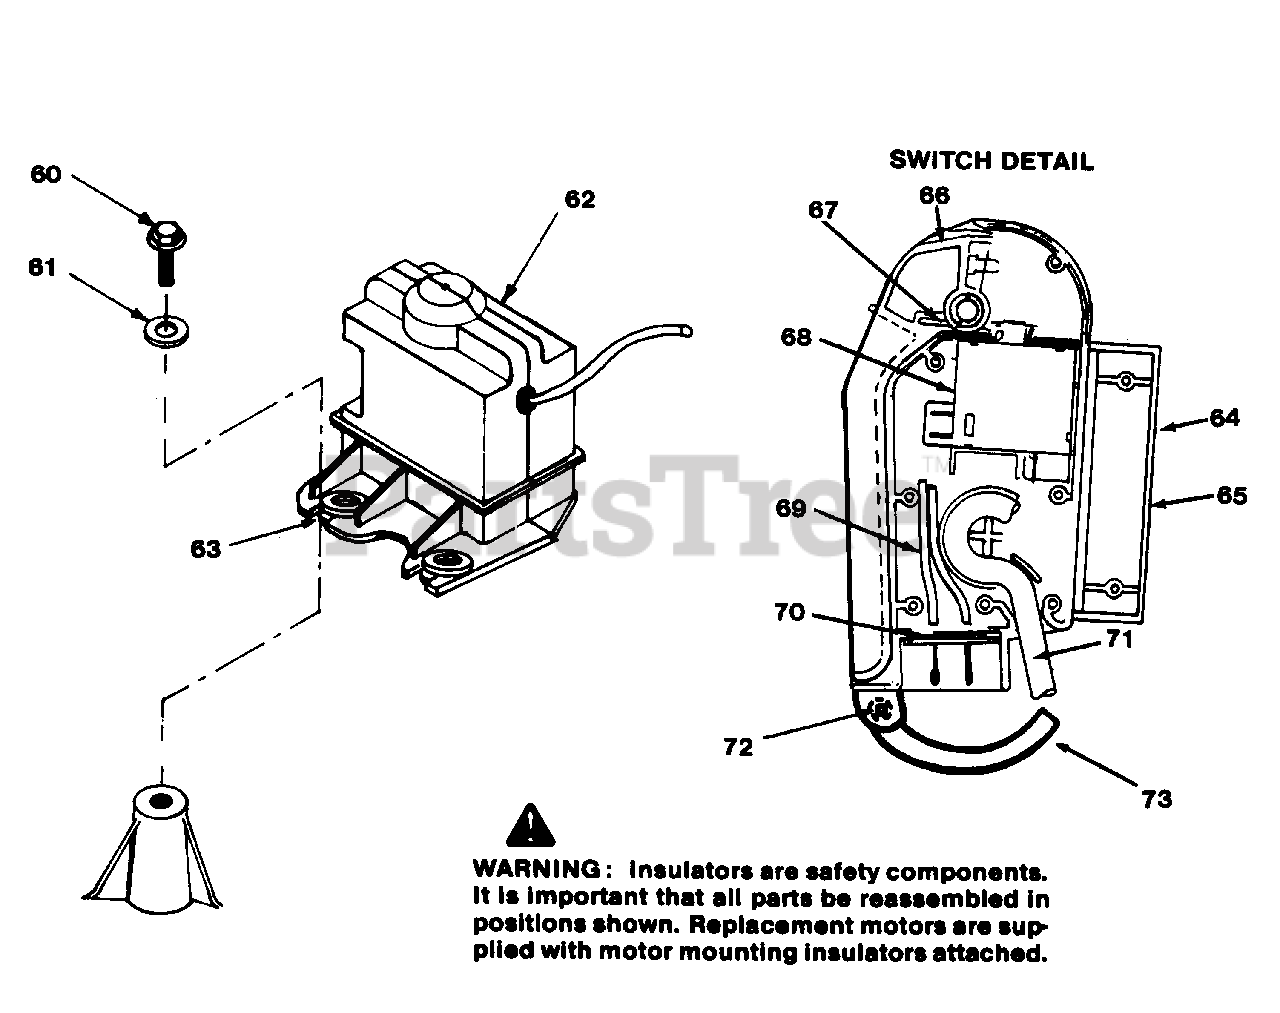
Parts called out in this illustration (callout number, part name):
60	Bolt, Motor Mount
61	Washer-1/4" ID x 3/4" OD x 1/16" Thick
62	Motor & Switch Assy.
63	Insulator, Motor Housing (Part of Key No 62)
64	Housing-Upper Half
66	Handle-Switch
69	Lead Ass'y (Black)
70	Prong Retainer (2-Pc)
71	Cord Ass'y.
72	Spring-Plug Ret
73	Plug Retainer
